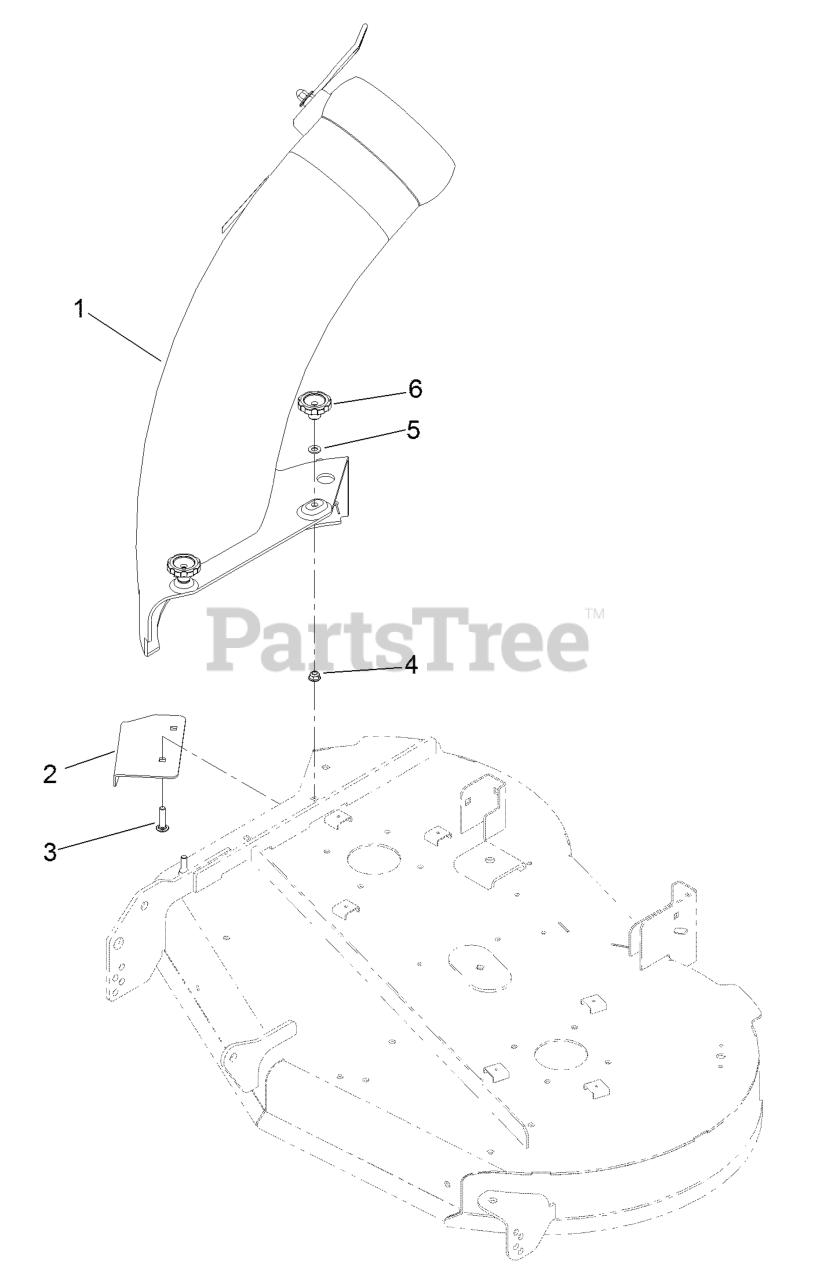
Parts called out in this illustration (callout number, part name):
1	CHUTE ASM
2	BAFFLE-CUTOFF
3	SCREW-CARR
4	NUT-HF, NI
5	WASHER-PLAIN
